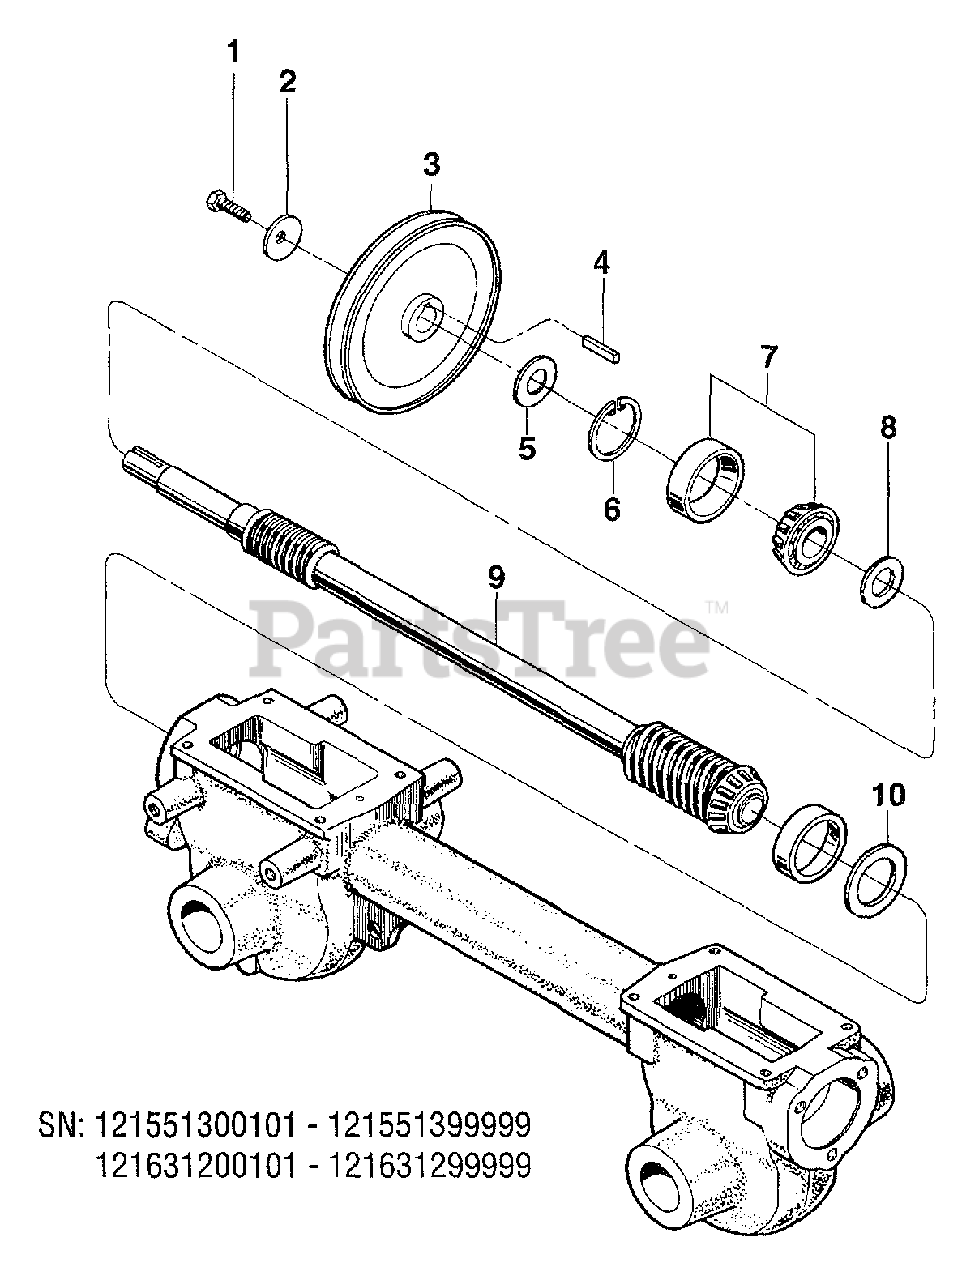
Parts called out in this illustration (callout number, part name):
1	Bolt-Hex Head, 5/16-24 x 3/4, Grade 5
2	Washer-Belleville
3	Pulley-Transmission
4	Key-Transmission Pulley, 3/16 x 11
5	Support Washer-Front
6	Snap Ring
7	Bearing-Tapered Roller with race
8	Support Washer-Rear
9	Drive shaft Assembly
10	Shim-Rear Bearing Cap, .010 thick
